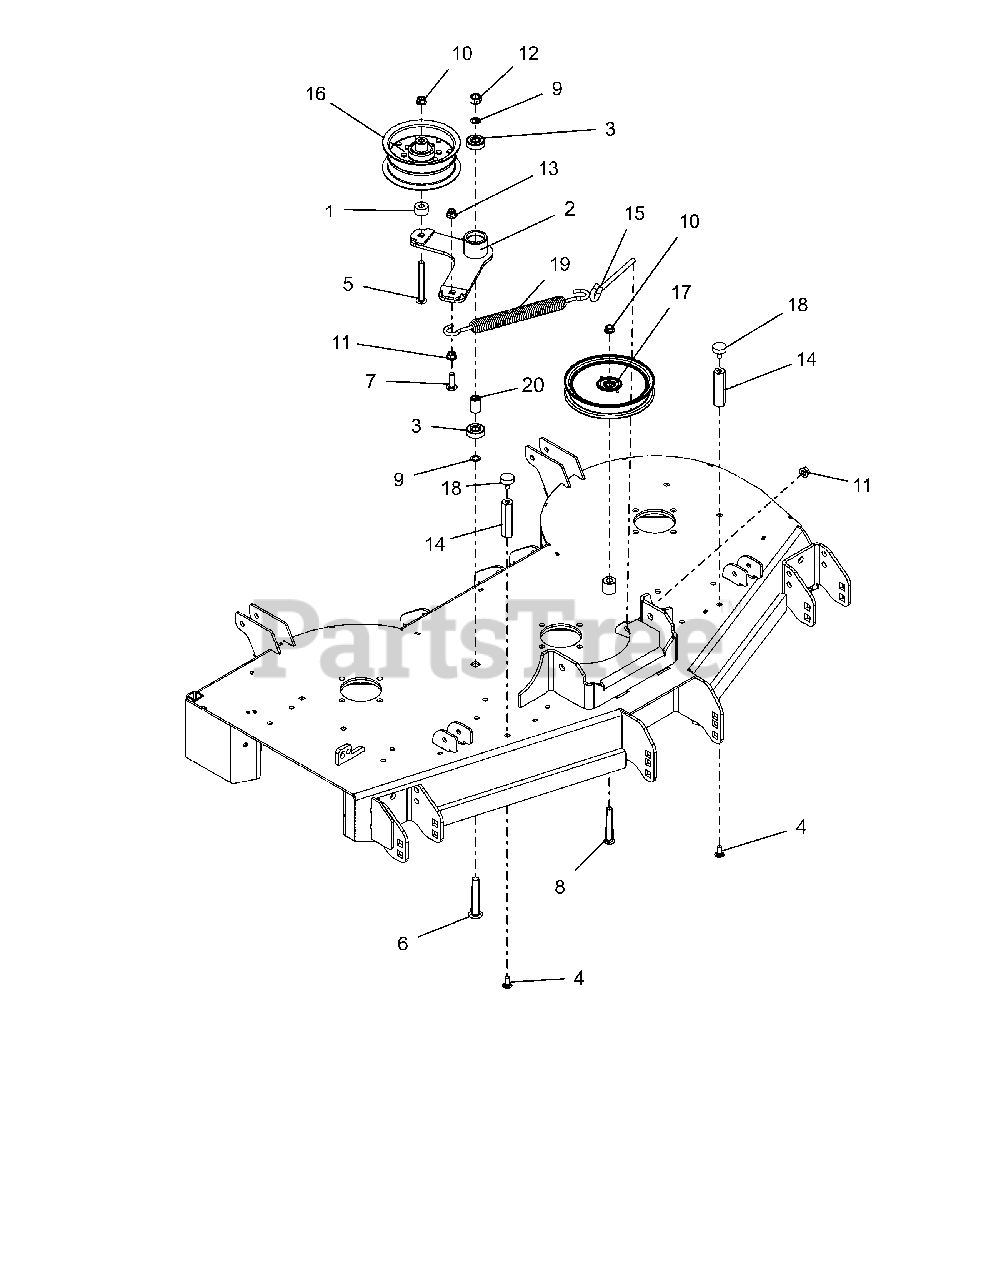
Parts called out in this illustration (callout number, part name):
1	SPACER .390X1.000X.562
2	WLDMT, DECK IDLER ARM
3	BRG-BALL .500X1.38X.437
4	BLT,RDHDSQNK .31-18X.75 LOCTIT
5	@BLT-RHDSSQNK .38-16X3.50 G5YZ
6	BLT,RDHDSQSHNK.50-13X3.25 G5YZ
7	@BLT-RHDSSQNK .38-16X1.25 G5YZ
8	@BLT-RDHDSQNK .38-16X3.00 G5YZ
9	WASHER, .500X.750X.020 THRUST
10	NUT-LK-CTR-FLG .38-16 YWZC
11	@NUT-SPNLK-FLG .375-16 YWZC
12	@NUT-LK-CTR .50-13 YWZC
13	@NUT-LK-NYL-FLG .38-16 YWZC
14	NUT, COUPLING .31-18 X 3.00
15	BOLT,.38-16 X 4.25-.62 DIA EYE
16	PULLEY, FLAT 5.00X2.36X.375
17	IDLER, FLAT-6.00" X .75"
18	BUMPER, RUBBER
19	SPRING, EXTENSION
20	SPACER .510 X .75 X 1.1485
